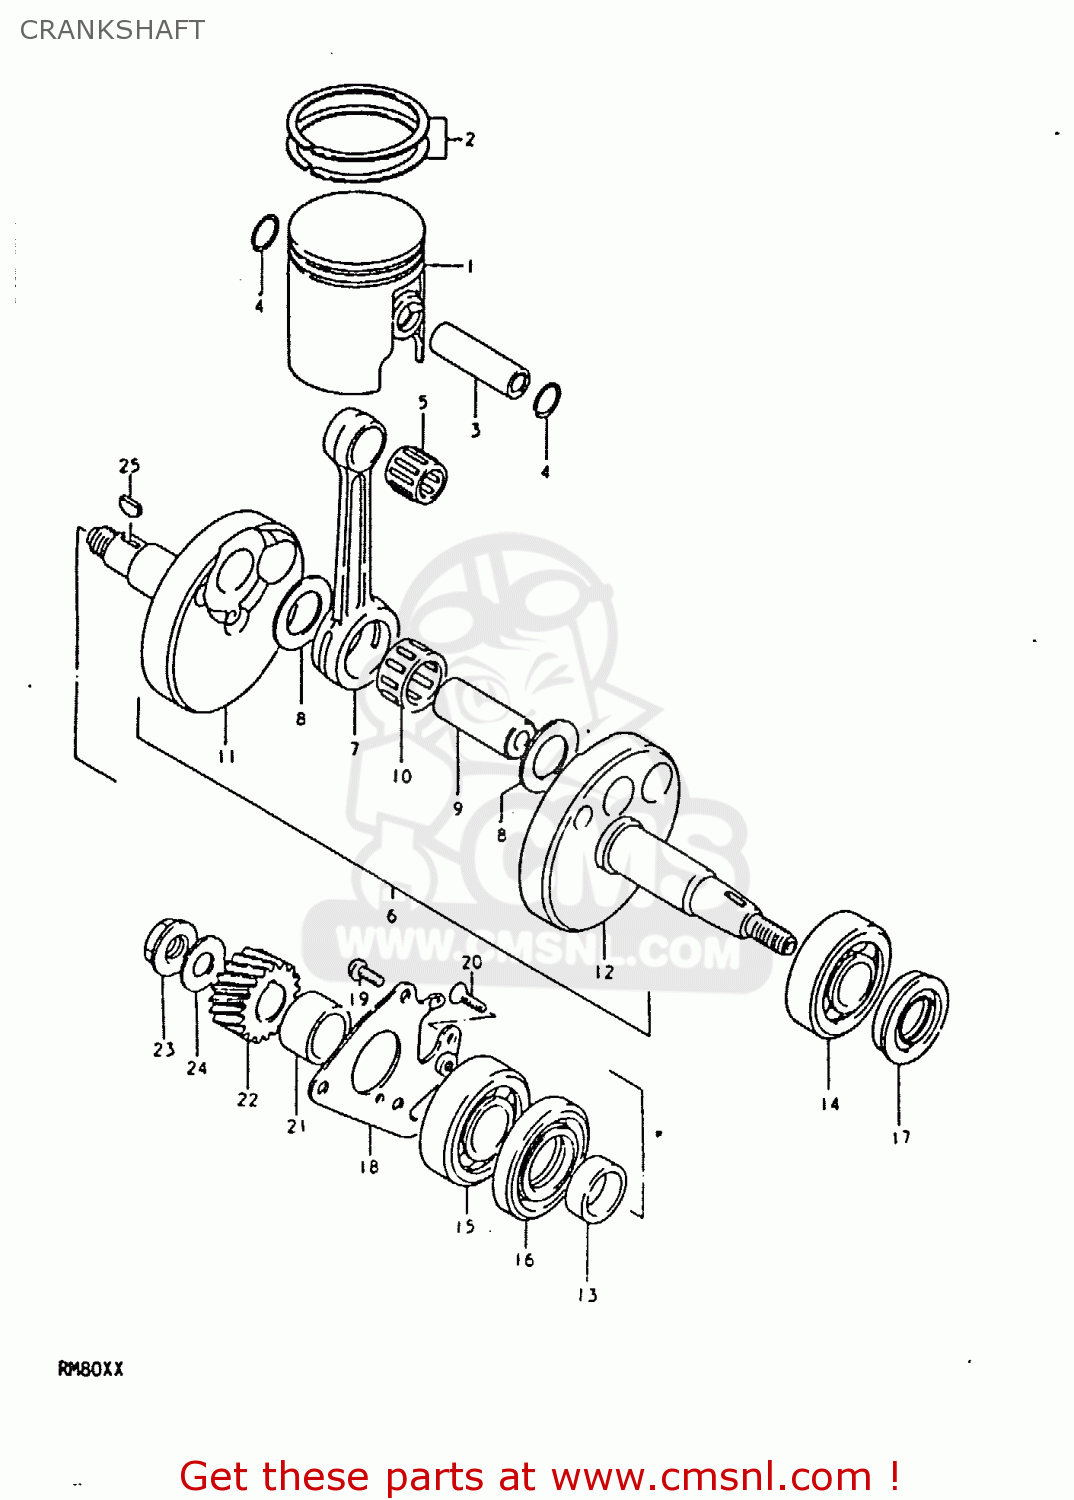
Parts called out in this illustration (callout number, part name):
1	PISTON (48.00MM)
2	RING SET,PISTON
3	PIN,PISTON
4	RING,SNAP
5	BEARING
6	CRANKSHAFT ASSEMBLY
7	ROD,CONNECTING
8	WASHER
9	PIN,CRANK
10	BEARING(17X23X14)
11	CRANKSHAFT
12	CRANKSHAFT,LEFT
13	SPACER
14	BEARING
15	BEARING
16	OIL SEAL
17	SEAL,OIL(19.6X37X8)
18	RETAINER
19	SCREW 6X12
20	SCREW
21	SPACER(20X26X14)
22	GEAR,PRIMARY DRIVE NO.19
23	NUT
24	WASHER
25	KEY
